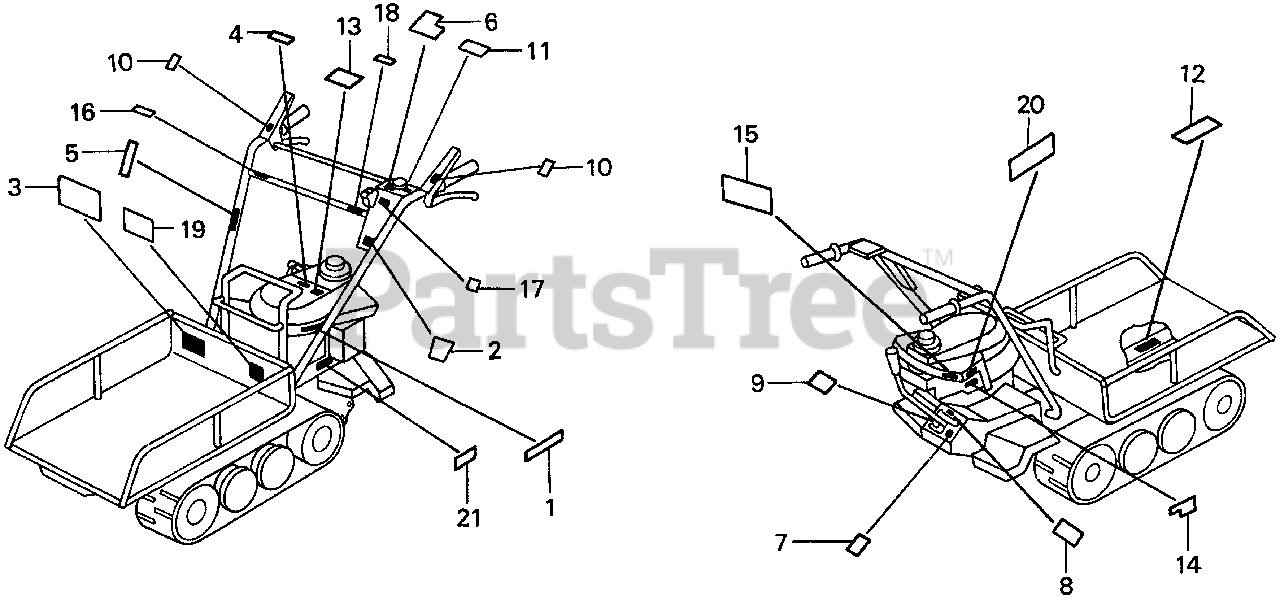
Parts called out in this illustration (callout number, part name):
1	EMBLEM
2	MARK, EMBLEM (ENGLISH)
3	MARK, CARRIER CAUTION (ENGLISH)
4	LABEL, FUEL CAUTION (ENGLISH)
5	MARK, LOCK LEVER
6	MARK, ENGINE SWITCH (ENGLISH)
7	MARK, POSITION INDICATION (ENGLISH)
8	MARK, POSITION INDICATION
9	MARK, POSITION INDICATION
10	MARK, CLUTCH INDICATION (ENGLISH)
11	LABEL C, CAUTION
13	LABEL A, CAUTION (ENGLISH)
14	MARK, AIR CLEANER CAUTION (ENGLISH)
16	MARK, R. SIDE CLUTCH (ENGLISH)
17	MARK, THROTTLE (ENGLISH)
18	MARK, L. SIDE CLUTCH (ENGLISH)
19	LABEL, MAXIMUM LOADAGE CAUTION
21	MARK, OIL CAUTION (ENGLISH)
